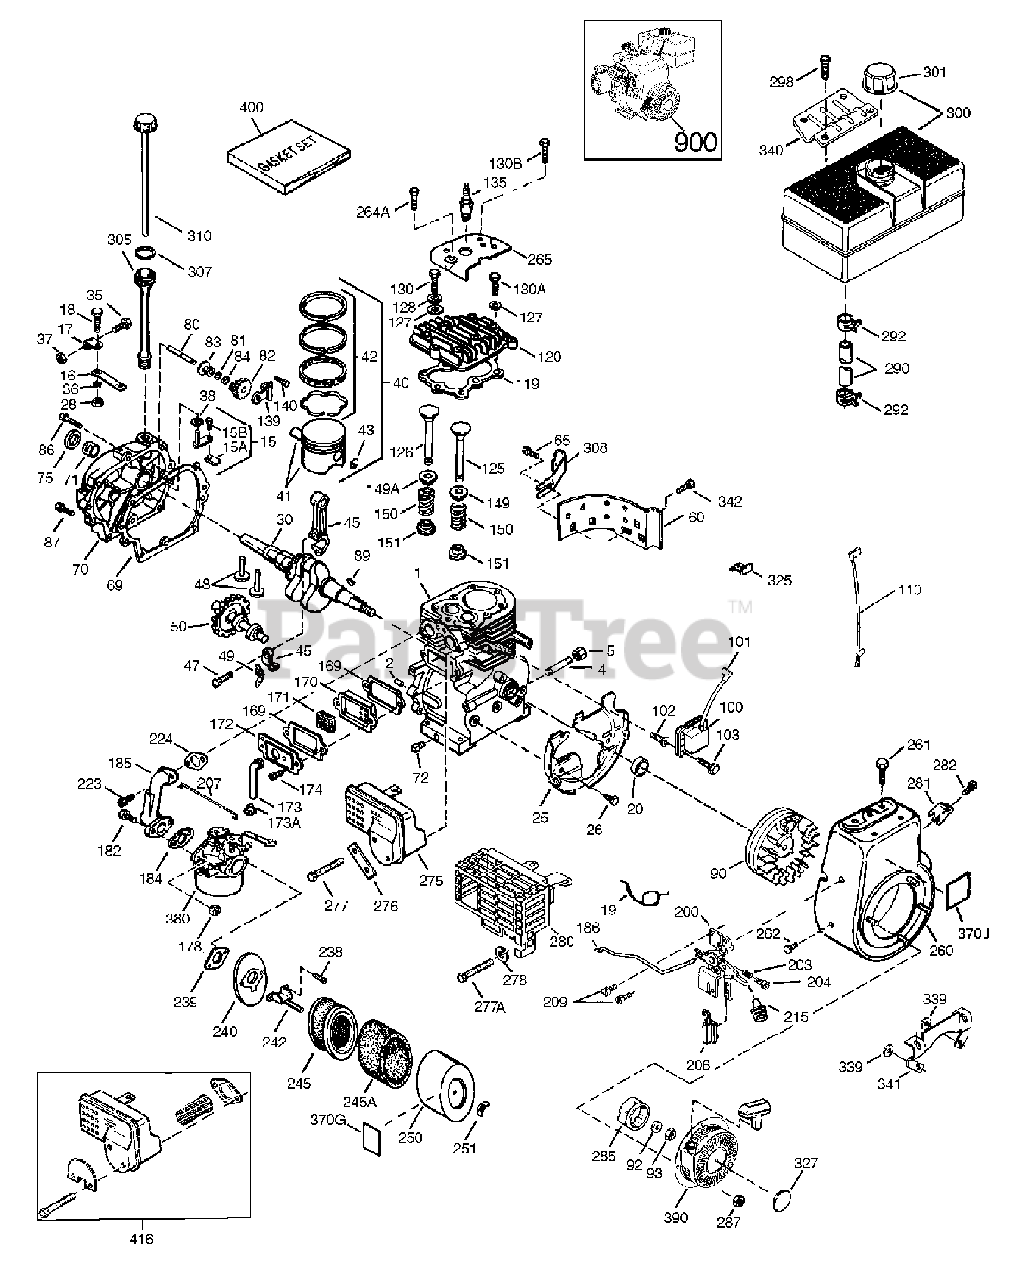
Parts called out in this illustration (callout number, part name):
1	Cylinder
2	Dowel Pin
4	Oil Drain Extension
5	Extension Cap
15	Governor Rod
15A	Governor Yoke
15B	Screw, 6-40 x 5/16"
16	Governor Lever
17	Governor Lever Clamp
18	Screw, Torx T-15, 8-32 x 3/8"
19	Speed Control Spring
20	Oil Seal
25	Blower Housing Baffle
26	Screw, 1/4-20 x 5/8"
28	Lock Nut, 8-32
30	Crankshaft
35	Screw, 10-32 x 3/4"
36	Lock Washer
37	Lock Nut, 10-32
38	Retaining Ring
40	Piston, Pin & Ring Set (std.)
40	Piston, Pin & Ring Set (.010" os)
41	Piston & Pin Assembly (std.)
41	Piston & Pin Assembly (.010" os)
42	Ring Set (std.)
42	Ring Set (.010" os)
43	Piston Pin Retaining Ring
45	Connecting Rod Ass'y
47	Connecting Rod Bolt
48	Valve Lifter
49	Oil Dipper
50	Camshaft (MCR)
60	Blower Housing Extension
65	Screw, 10-24 x 1/2"
69	Cylinder Cover Gasket
70	Cylinder Cover
71	Crankshaft Bushing
72	Oil Drain Plug
75	Oil Seal
80	Governor Shaft
82	Governor Gear Ass'y.
83	Governor Spool
84	Retaining Ring
86	Screw, 1/4-20 x 1-3/16"
87	Screw, 1/4-20 x 1-11/16"
89	Flywheel Key
90	Flywheel
92	Lock Washer
93	Flywheel Nut
100	Solid State Ignition
101	Spark Plug Cover
102	Solid State Mounting Stud
103	Screw, Torx T-15, 10-24 x 15/16"
110	Ground Wire
119	Cylinder Head Gasket
120	Cylinder Head
125	Exhaust Valve (std.)
125	Exhaust Valve (1/32" os)
126	Intake Valve (std.)
126	Intake Valve (1/32" os)
128	Belleville Washer
130	Screw, 5/16-18 x 2"
130A	Screw, 5/16-18 x 5/8"
130B	Screw, 1/4-20 x 9/16"
135	Resistor Spark Plug
139	Governor Gear Bracket
140	Screw, 10-24 x 1/2"
149	Valve Spring Cap
149A	Valve Spring Cap
150	Valve Spring
151	Valve Spring Keeper
169	Breather Gasket
170	Breather Body
171	Breather Element
172	Valve Cover
173	Breather Tube
173A	Breather Tube Grommet
174	Screw, 10-24 x 1/2"
178	Nut & Lock Washer
182	Screw, 1/4-28 x 1"
184	Carburetor to Intake Pipe Gasket
185	Intake Pipe
186	Governor Link
200	Control Bracket
203	Compression Spring
204	Screw, Torx T-10, 5-40 x 7/16"
206	Terminal
207	Throttle Link
209	Screw, 10-32 x 1/2"
215	Control Knob
223	Screw, Torx T-30, 5/16-18 x 1-1/8
224	Intake Pipe Gasket
238	Screw, 10-32 x 1/2"
239	Air Cleaner Gasket
240	Air Cleaner Bracket
242	Air Cleaner Bracket
245	Air Cleaner Filter
245A	Air Cleaner Filter
250	Air Cleaner Cover
251	Wing Nut, 1/4-20
260	Blower Housing
261	Screw, 5/16-18 x 3/4"
262	Screw, Torx T-40, 5/16-24 x 21/32"
264A	Screw, 1/4-20 x 5/8"
265	Cylinder Head cover
275	Muffler
276	Locking Plate
277	Screw, 5/16-18 x 3-3/16"
277A	Screw, 5/16-18 x 3-31/32"
278	Heat Shield Spacer
280	Heat Shield
281	Starter Bubble Cover
282	Screw, 8-32 x 3/8"
285	Starter Cup
287	Nut & Lock Washer
290	Fuel Line
292	Fuel Line Clamp
298	Screw, 1/4-15 x 3/4"
300	Fuel Tank
301	Fuel Cap
305	Oil Fill Tube
308	Fill Tube Clip
310	Dipstick
325	Wire Clip
327	Starter Plug
340	Fuel Tank Bracket
341	Fuel Tank Bracket
342	Screw, Torx T-30, 1/4-20 x 1/2"
370G	Oil Instruction Decal
370J	Throttle Decal
380	Carburetor
390	Rewind Starter
400	Gasket Set
416	Spark arrester Kit
900	Replacement Engine none
